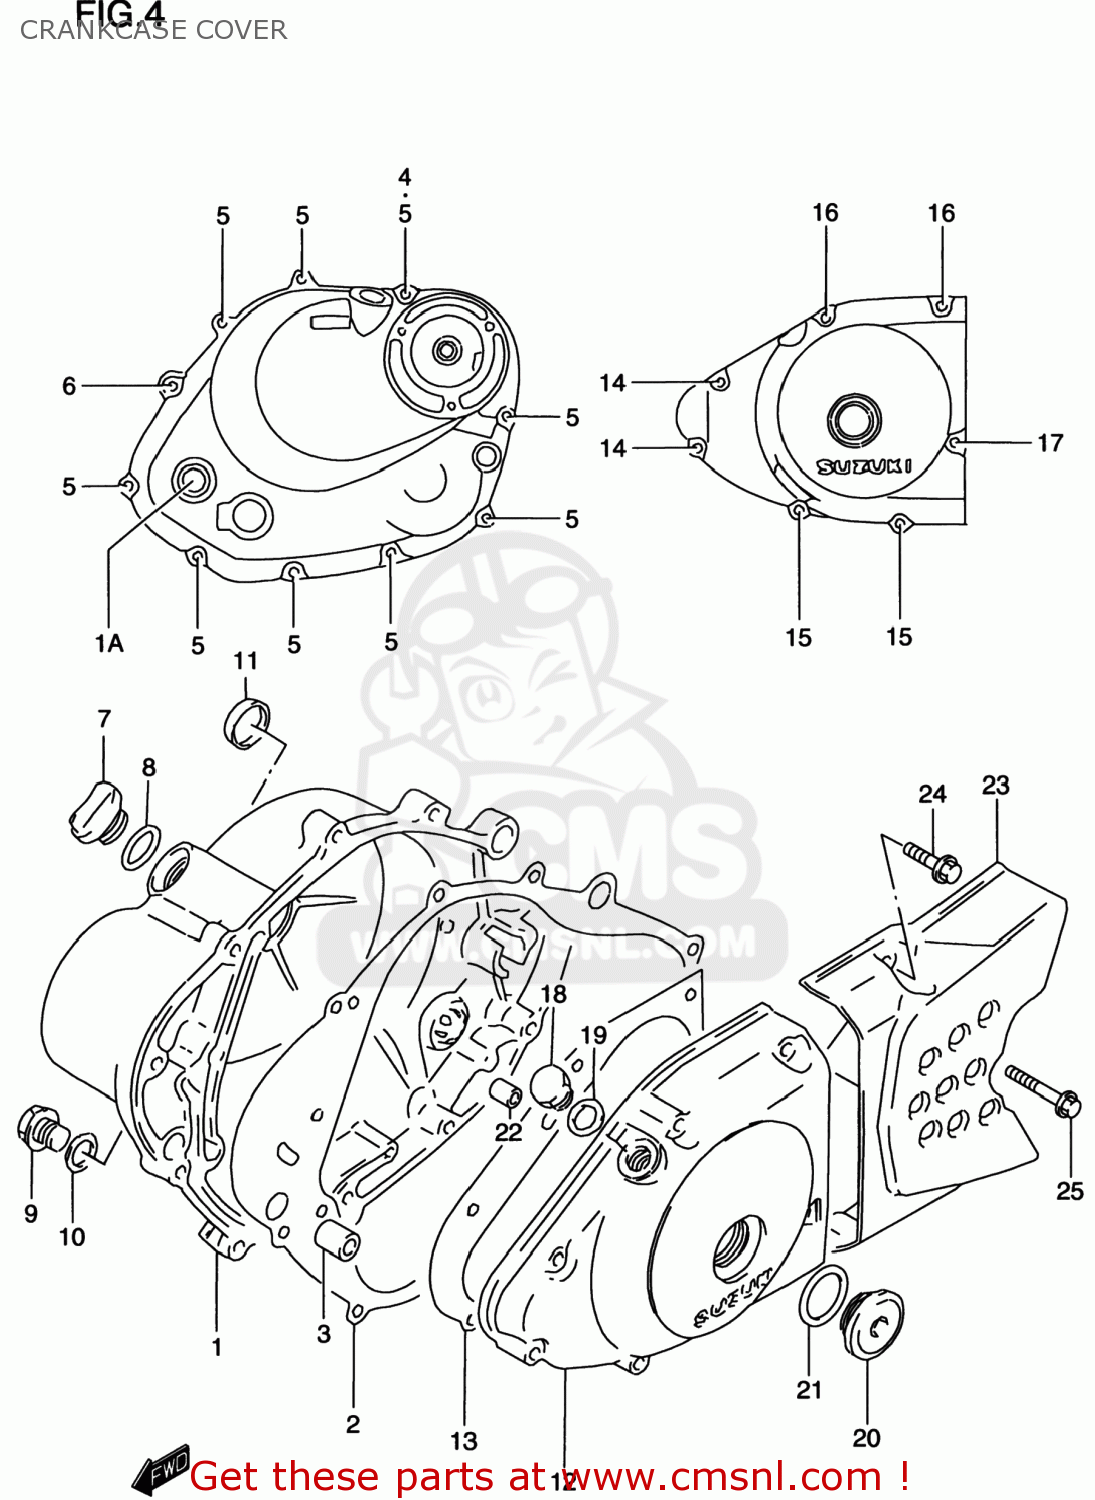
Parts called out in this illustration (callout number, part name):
1	COVER,CLUTCH
1A	LENS,OIL LEVEL CHECK
2	GASKET,CLUTCH COVER (NAS)
3	PIN
4	GASKET(5.8X11X1.2) (NAS)
5	BOLT,G/S SWITC
6	BOLT
7	PLUG
8	O RING(D:3.1,ID:16.8)
9	PLUG(14X12)
10	GASKET(13.8X18.8X4.8) (NAS)
11	PLUG,CLUTCH COVER KICK
12	COVER,MAGNETO
13	GASKET,MAGNETO COVER (NAS)
14	BOLT,G/S SWITC
15	BOLT
16	BOLT
17	BOLT
18	PLUG,12X9
19	GASKET(12.1X16.2X3.7) (NAS)
20	PLUG(26X9)
21	O RING(D:3.1,ID:22.7)
22	PIN
23	COVER,ENGINE SPROCKET
24	SCREW
25	BOLT
